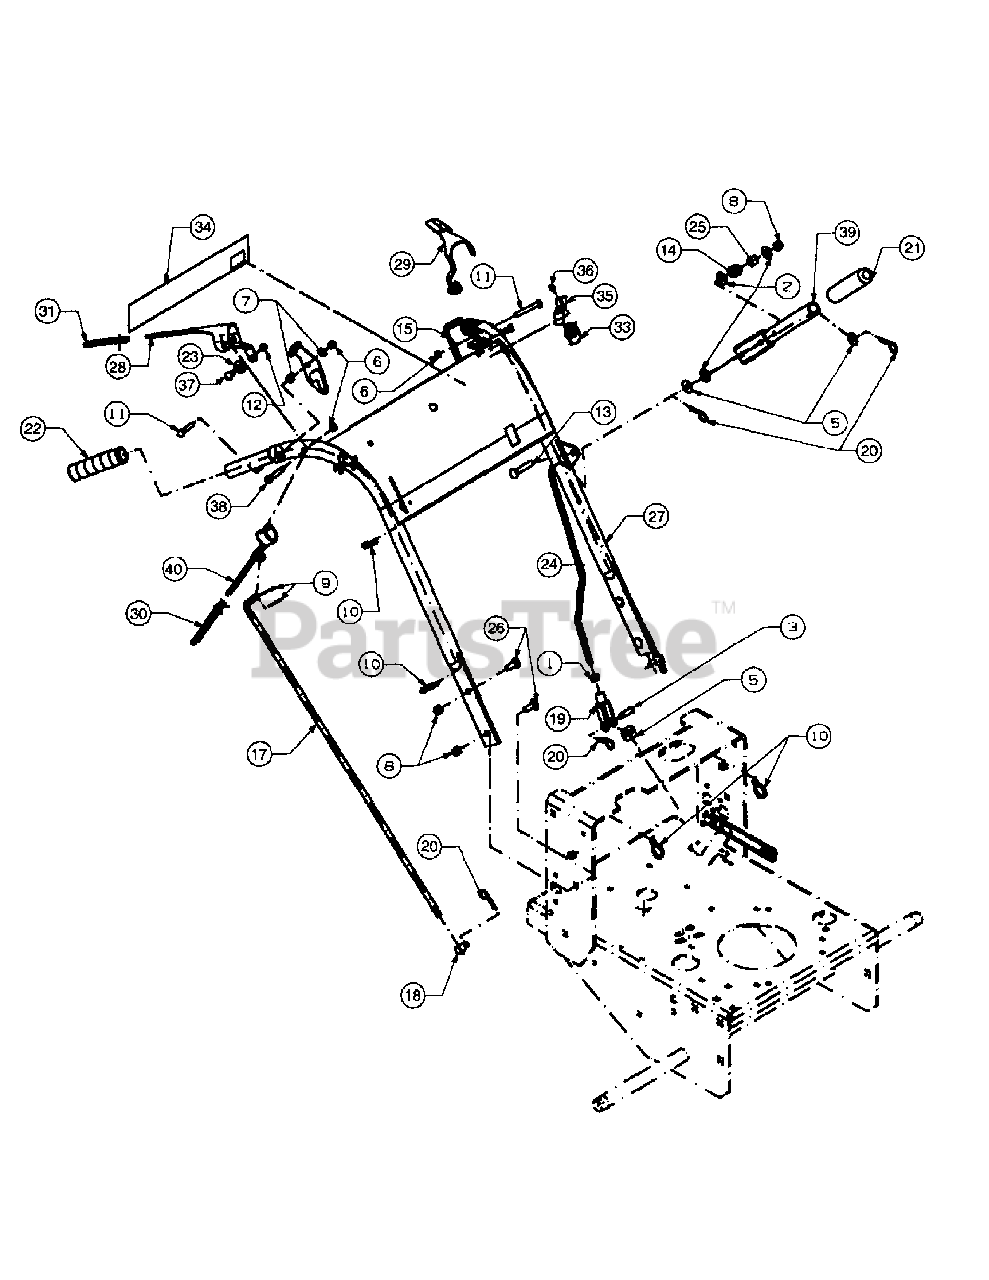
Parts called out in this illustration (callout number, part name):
1	Hex Nut, 3/8-16
2	Flat Washer, 3/8 Zinc
3	Clevis Pin, 3/8 x 1-1/8 Zinc
4	Grip, Neutral Latch, 1.25"
5	Flat Washer, 3/8 Zinc
6	Nylock Nut, 5/16-18
7	Flat Washer, 5/16 Zinc
8	Lock Nut, Nylon Insert, 3/8-16
9	Cotter Pin, 3/32 x 3/4, Zinc
10	Cable Tie, 3/16 x. 05 x 7.4
11	Hex Cap Screw, 5/16-18 x 2
12	Lock Nut, Nylon Insert
13	Carriage Bolt, 3/8-16 x 2
14	Spring, .850 OD x 1
15	Neutral Latch, Left Hand
16	Neutral Latch, Right Hand
17	Steering Control Rod
18	Joint Swivel
19	Yoke, 3/8-16 Female
20	Hair Pin 3/8-1/2
21	Handle Grip, Black, 1"
22	Plastic Handle Grip, Black, 4-5/8
23	Control Rod, Hydro Spacer
24	Hydro Blade Clutch Rod Base
25	Spring Sleeve
26	Carriage Bolt, 3/8-16 x 2
27	Handle Assembly Hydro
28	Operator Presence Control RH
29	Operator Presence Control LH
30	Control Sleeve, Black
31	Operator Control Sleeve, Yellow
32	Harness Assembly Adapter
33	Switch Mounting Snap
34	Handle Label, Rear, 5 Speed
35	Operator Presence Return Spring
36	Hex Index Washer Screw, 0.500
37	Shoulder Screw, .38 x .412, 1/4-28
38	Hex Cap Screw, 5/16-18, 2.00
39	Blade Clutch Lever
40	Lever Assembly Control
